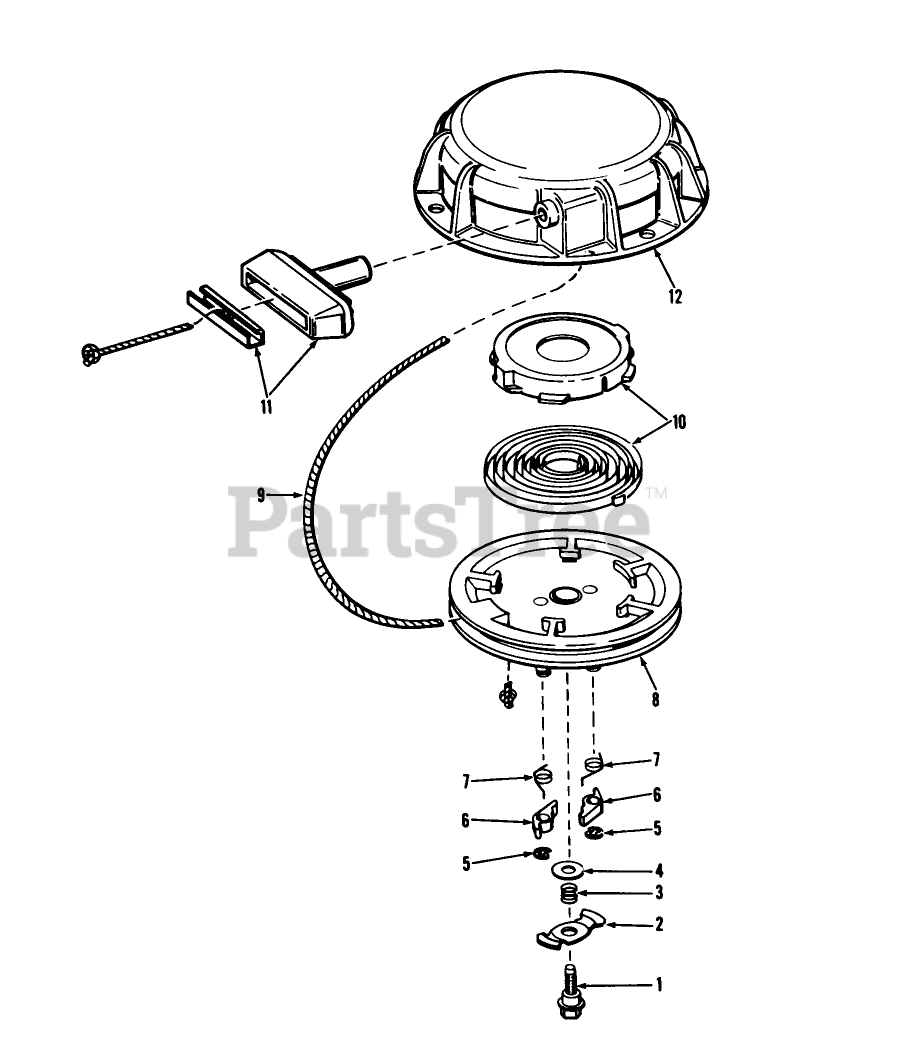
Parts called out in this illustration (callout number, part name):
1	Screw, Center
2	Cam, Dog
3	Spring, Brake
4	Washer, Brake
5	Ring, Retainer
7	Spring, Dog
8	Pulley
9	Rope-Starter
10	Spring & Keeper Assy.
11	Assy., Starter
12	Housing Assy., Starter
